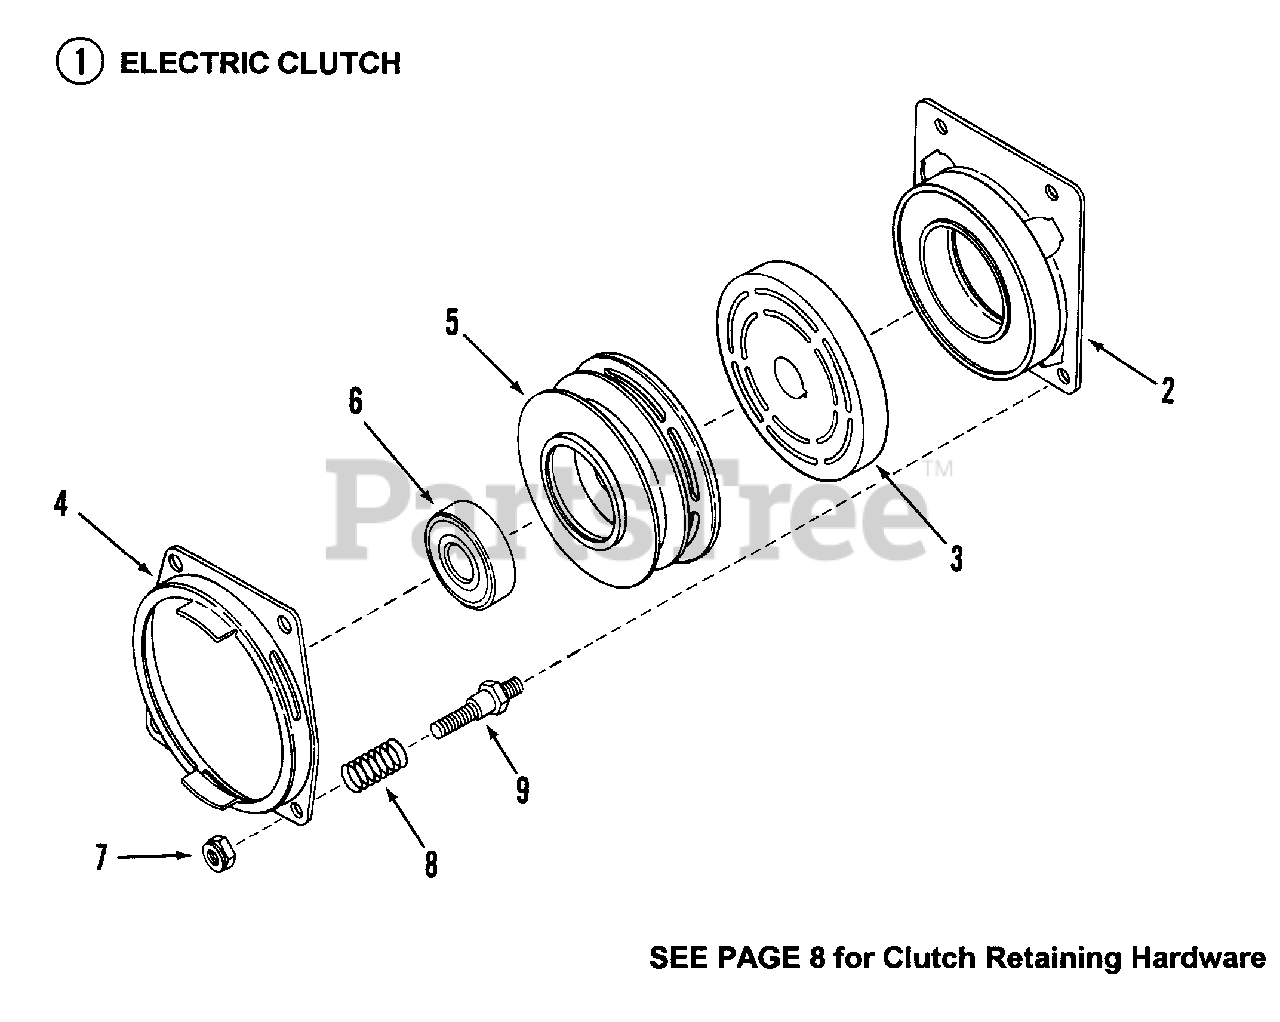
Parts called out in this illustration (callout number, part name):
1	KIT, Electric Clutch
2	FIELD COIL
3	ROTOR
4	COVER, Brake
5	ASSEMBLY, Arm-Pulley
6	BEARING, Ball
7	NUT, 3/8-24 Hex Nylok
8	COIL SPRING
9	STUD, 3/8 Threaded
